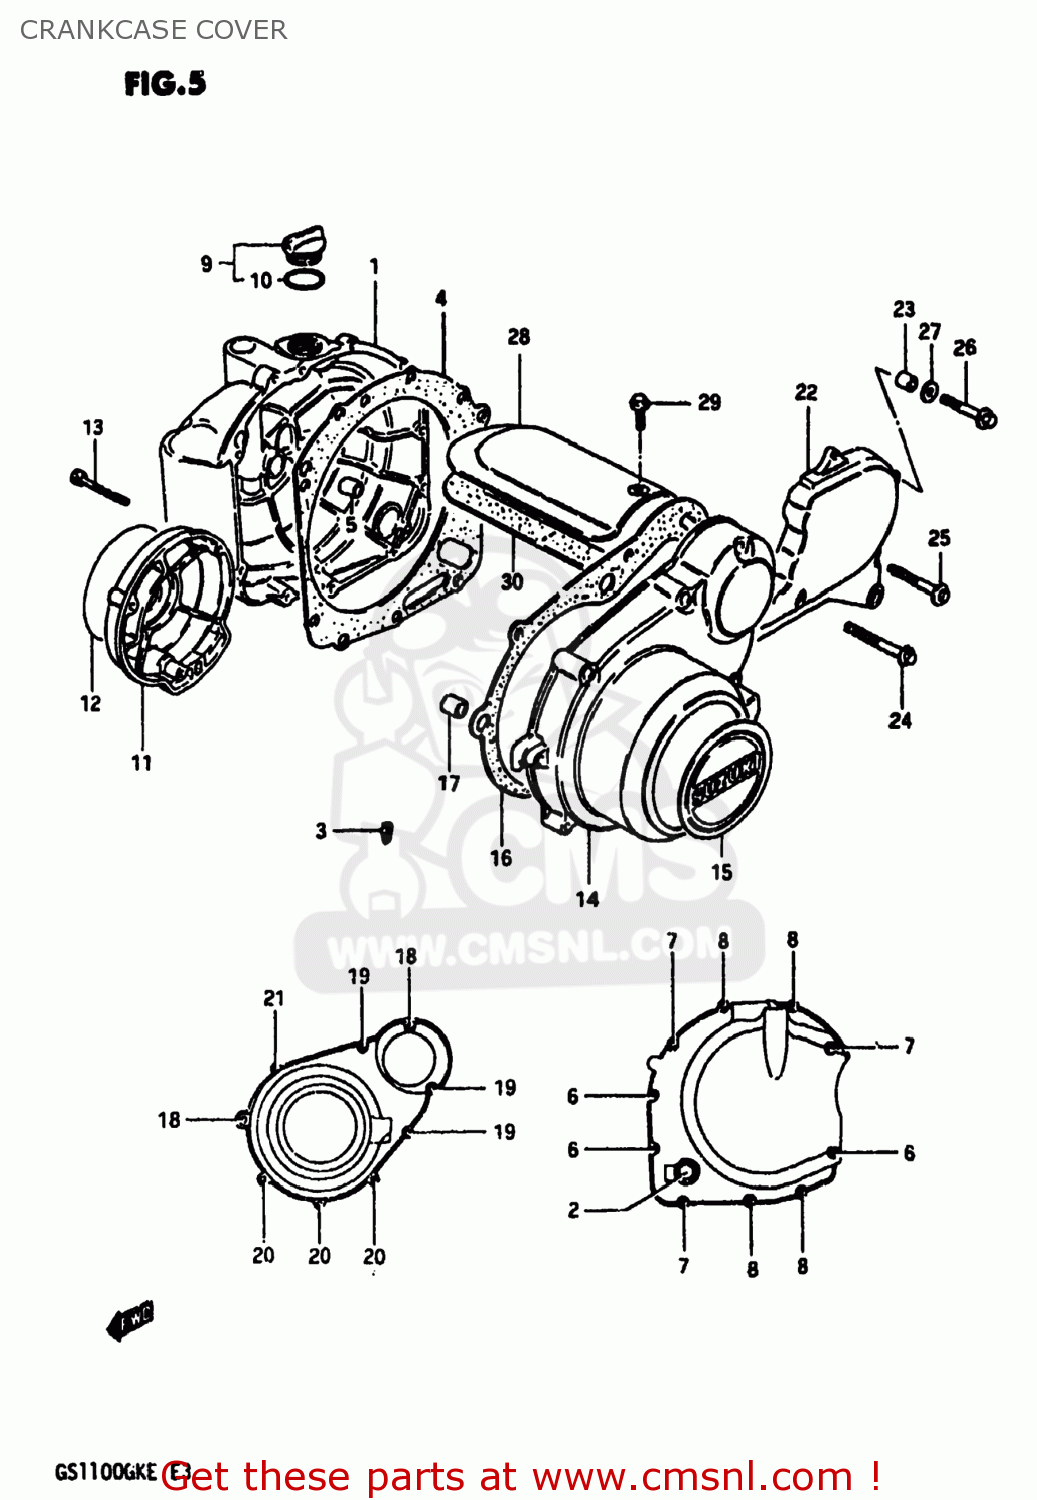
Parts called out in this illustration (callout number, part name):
1	COVER,CLUTCH
2	LENS,OIL LEVEL CHECK
3	JET
4	GASKET,MAGNETO COVER (N (MCA)
5	PIN
6	BOLT (6X35)
7	BOLT (6X30)
8	BOLT
9	PLUG SET
10	O RING(D:2.2,ID:32)
11	COVER,CONTACT BREAKER
12	EMBLEM,CONTACT BREAKER COVER
13	BOLT (5X30)
14	COVER,MAGNETO
15	EMBLEM,MAGNETO COVER
16	GASKET,MAGNETO COVER (MCA)
17	PIN
18	BOLT
19	BOLT (6X40)
20	BOLT (6X35)
21	BOLT (6X30)
22	COVER,SECONDARY DRIVE
23	PIN
24	BOLT (6X30)
25	BOLT
26	BOLT (6X20)
27	WASHER
28	COVER,STARTER MOTOR
29	BOLT
30	GASKET,STARTER MOTOR COVER (MCA)
